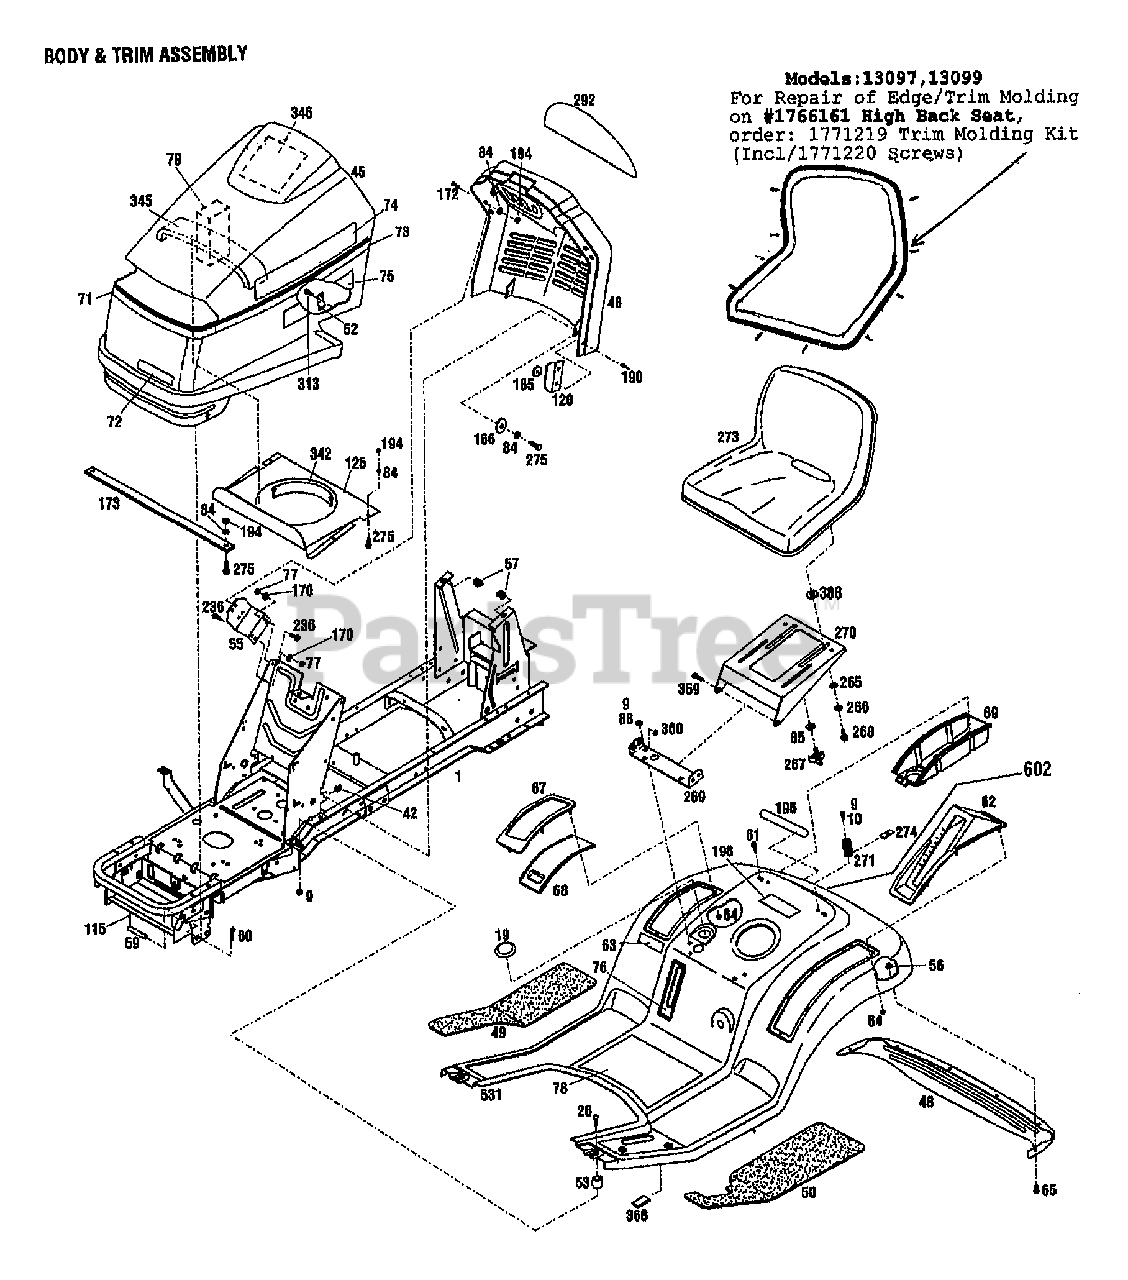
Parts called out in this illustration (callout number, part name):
1	ASSM-FRAME LTX {13096/097}
1	ASSM-FRAME {13099}
9	NUT-HFLK 5/16-18 ZP
10	SCR-HHC 5/16-18X.75 GR 5 ZP
19	PLUG 2.50
26	SCR-CARR 5/16-18X1.0 G2 ZP
42	NUT-SPEED
45	HOOD-TRACTOR
46	CONSOLE
48	TRIM-FENDER REAR
49	PAD-FOOT RH
50	PAD-FOOT LH
52	LATCH
53	SPACER-TUBULAR
55	BRKT-MOUNTING
56	NUT-HF/LK 1/4-20 ZP
57	NUT-SELF RETAIN 5/16-18
59	PIN-PIVOT HOOD
60	PIN-HITCH .125X2.56 ZP
61	SCR-LOCK
62	COVER-LIFT HANDLE {13096/097}
63	DECAL-AMERICAN LEGEND-LRG
64	NUT-SELF THREADING
65	SCR-HH 1/4-20X.625
67	TOP-STORAGE COVER
68	COVER-CONTAINER
69	CONTAINER-STORAGE
71	DECAL-STRIPE HOOD FRONT
72	DECAL-LOGO
73	DECAL-STRIPE SIDE
74	DECAL-LOGO TROY-BILT
75	DECAL-HYDRO
76	DECAL-FUEL LEVEL
77	NUT-HEX 5/16-18 ZP
78	DECAL-TUNNEL {13096}
78	DECAL-OPER INST {13097}
78	DECAL-TUNNEL {13099}
79	BLOCK-SEALING {13099}
84	WASHER-LK .25 ZP
85	WASHER-FLAT 3/8 SAE
88	SCR-CARR 5/16-18X.62 G2 ZP
115	PIN-ROLL .188X1.0
120	BRKT-HOOD ALIGN
125	SHIELD-HEAT UPPER {13099}
165	WASHER-.88X.2X.059
166	WASHER-FLAT 1.25X.28X.062 ZP
170	WASHER-LK .312 ZP
173	STRAP-HOOD
190	RIVET-POP
194	NUT-HEX 1/4-20 ZP
196	DECAL-LOGO FENDER
198	DECAL-FUEL
236	SCR-HFLK 5/16-18X.75 ZP
265	WASHER-1.06X.51X.09 NYLON
266	WASHER-BOW .74X.52X.01
268	SCR-SHLDR 3/8-16X.25 G5ZP
269	BRKT-SUPPORT SEAT
270	SUPPORT-SEAT
271	SPRING-COMPRESSION
273	KIT-SEAT (TRACTOR) {13096}
273	KIT-SEAT (TRACTOR) {13097/099}
274	BRKT-SPRING HOLD DOWN
275	SCR-HH 1/4-20X.625 G5 ZP
292	LENS-WARNING LIGHTS {13096/097}
292	LENS-INSTRMTS WARN LIGHTS {13099}
342	GASKET-HEAT SHIELD {13099}
345	STRIP-SEALING {13099}
346	DECAL-SERVICE
359	SCR-HH 3/8-16X.88 G5 ZP
360	NUT-H/LK 3/8-16
388	WASHER-FLAT
531	FENDER-REAR
602	DECAL-LTX 13.5 RED {13096}
602	DECAL-LTX 15.5 RED {13097}
602	DECAL-LTX 16 RED {13099}
